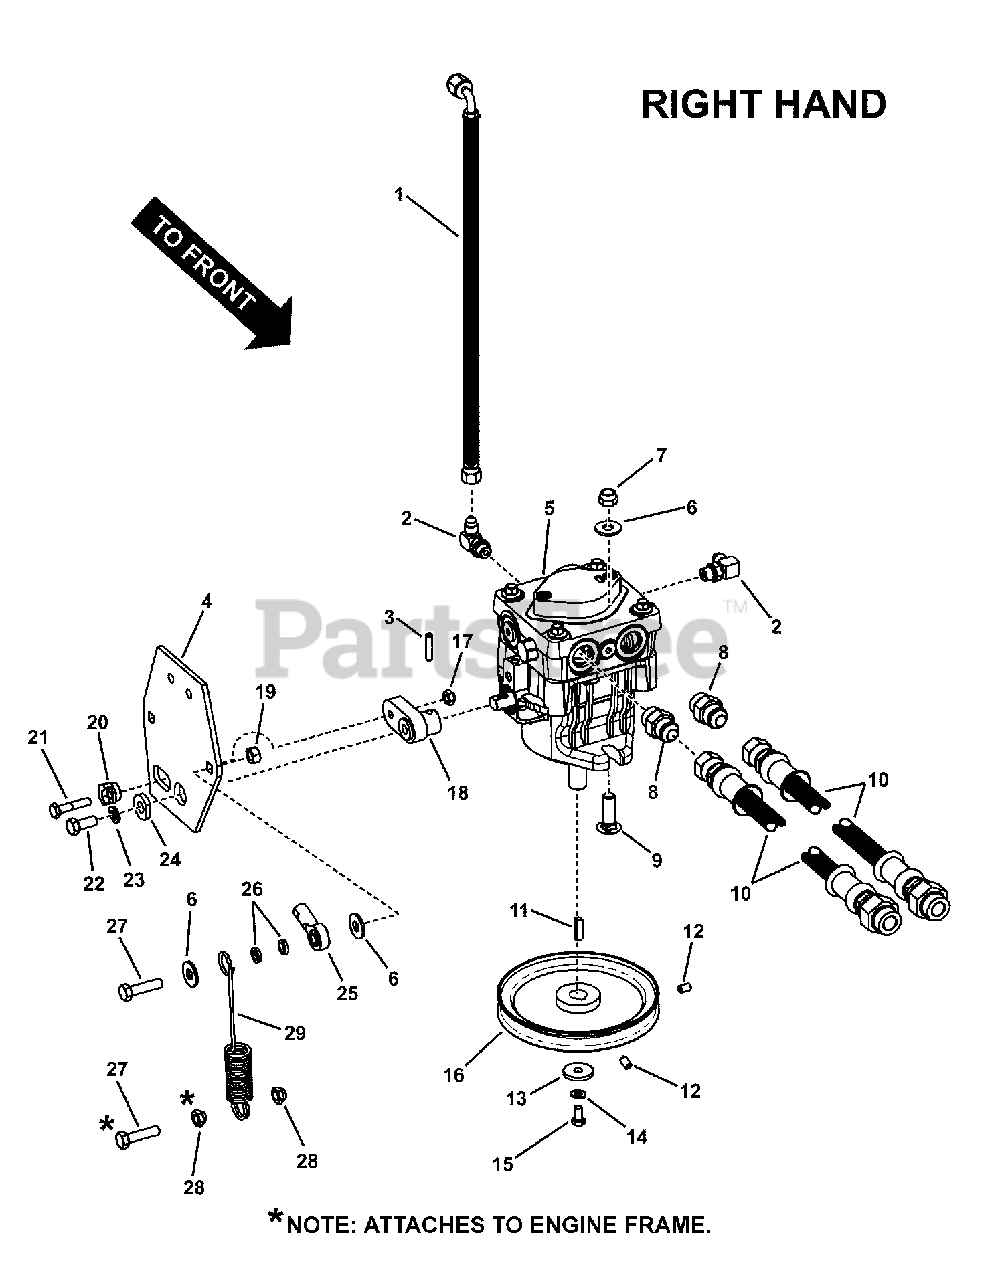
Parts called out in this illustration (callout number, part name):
1	HOSE ASSEMBLY, Pro Hydro Series 3 (13.5" hose length)
2	FITTING, 90 Degree- "O"-Ring Boss
3	ROLL PIN, 5mm x 25mm
4	SHIFT ARM, Pump
5	PUMP, Hydraulic, RH, HG, Pro Ser. 3
6	WASHER, 3/8" I.D. x 7/8" O.D. x 1/16" Flat
7	NUT, 3/8-16, HEX TOP LOCK
8	FITTING, Hydraulic, Straight 3/4-16 UNF
9	BOLT, 3/8-16 x 1-1/4" Short Neck Carriage, GR 5
10	HOSE, Pump/Motor, High Pressure 21-1/2"
11	KEY, M5 x M20
12	SET SCREW, 1/4-20 X 3/8" CONE
13	WASHER, 1/4" Flat
14	WASHER, 1/4" I.D. Split Lock
15	SCREW, M6 1.0X12MM, Hex Head, CZ
16	PULLEY, 5.5 w/Set Screws
17	NUT, 1/4-20 Hex Top Lock, GR B
18	ARM, Pump
19	NUT, 5/16-18 Hex Center Lock, GR 5 or B
20	ECCENTRIC
21	SCREW, 1/4-20 x 1-1/4, Hex Head Cap, GR 5
22	BOLT, 5/16-18 X 3/4 GD5
23	WASHER, .32 x .58 x .08 Split Lock
24	SPACER, Blade Hub
25	ROD END, Pump Control Linkage (5/16-24 thread)
26	BUSHING, Spring
27	BOLT, 5/16-18 X 1-1/4 GD5 YZ
28	NUT, 5/16-18 Hex Top Lock, GR B
29	SPRING, Hydro
